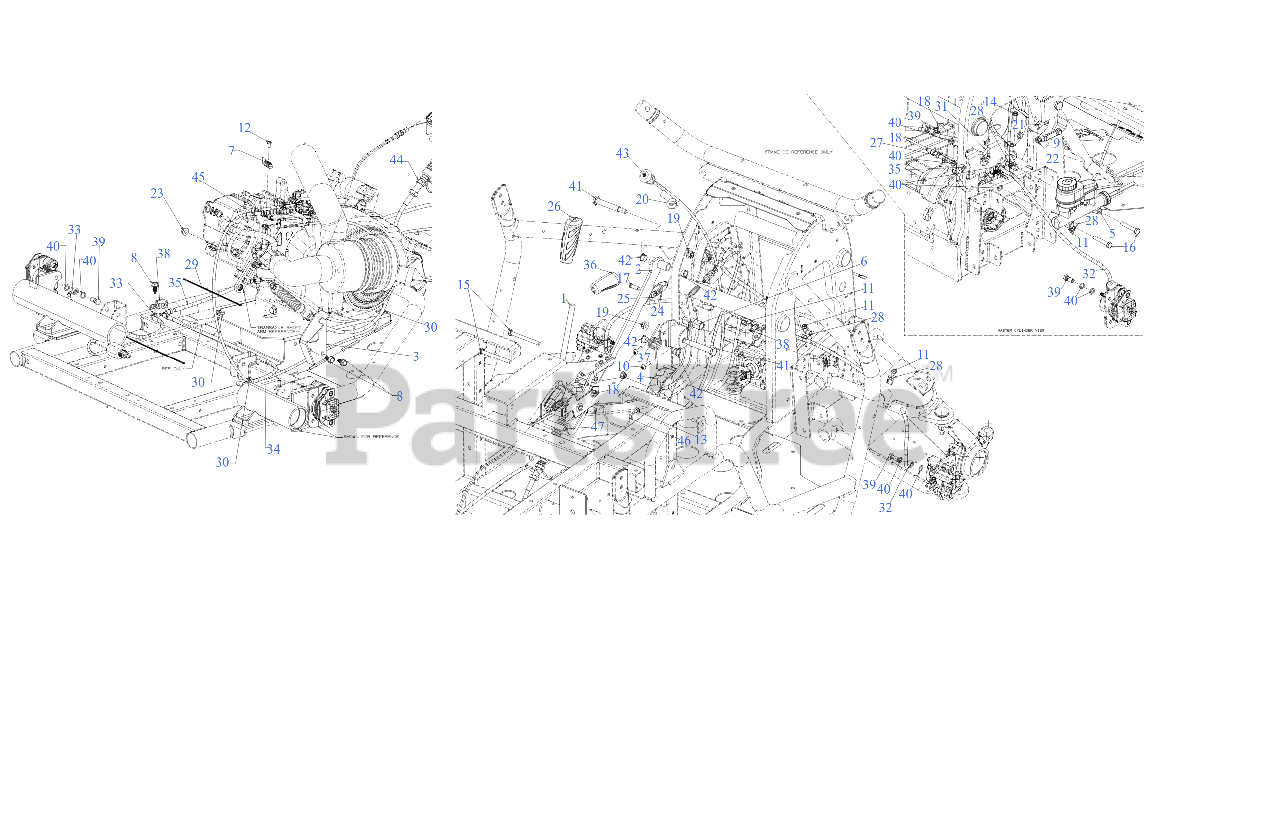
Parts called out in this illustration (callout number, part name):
1	SHIFT CONTROL ASSEMBLY
3	SHIFT BRACKET WELD ASSEMBLY
5	MASTER CYLINDER ASSEMBLY
7	THROTTLE BRACKET
8	SCREW 5/16-18 x .750
9	CARRIAGE BOLT 5/16-18 x 2.00 GR5
10	SCREW 1/4-20 x 1.0
11	SCREW 1/4-20 X.500
12	SCREW M5-.8X10MM SLOT/TORX
13	SCREW M6-1 x .625
14	SCREW 1/4-20 x .750
15	SCREW 5/16-18 x 3.25 GR5
16	SCREW 5/16-18 x 2.0 GR5
17	CLEVIS PIN .312 x 1.0
18	FLANGE LOCK NUT 5/16-18
20	ASSEMBLY
21	HEX NUT 5/16-18
22	HEX JAM NUT 5/16-24 GR 5
23	HEX FLANGE NUT M8X
24	BOW TIE COTTER PIN 1/4-5/16
25	ADJUSTABLE ROD END
27	BRAKE SWITCH
28	MOUNTING CLAMP
29	TIE CABLE 8.5 LG
30	CABLE TIE
31	BRAKE HOSE (FRONT MASTER CYLINDER)
32	BRAKE HOSE (FRONT)
33	BRAKE HOSE (LEFT HAND REAR)
34	BRAKE HOSE (RIGHT HAND REAR)
35	BRAKE HOSE (REAR MASTER CYLINDER)
36	BRAKE HANDLE GRIP
37	TORSION SPRING
38	TEE FITTING
39	BANJO FITTING
40	BANJO FITTING
41	SHOULDER BOLT .50 x 2.5 x 3/8 -16
42	NYLINER BEARING
43	CHOKE CABLE 93"
44	SHIFT CABLE 44"
45	THROTTLE CONTROL CABLE 108"
46	CABLE GUIDE ROD
